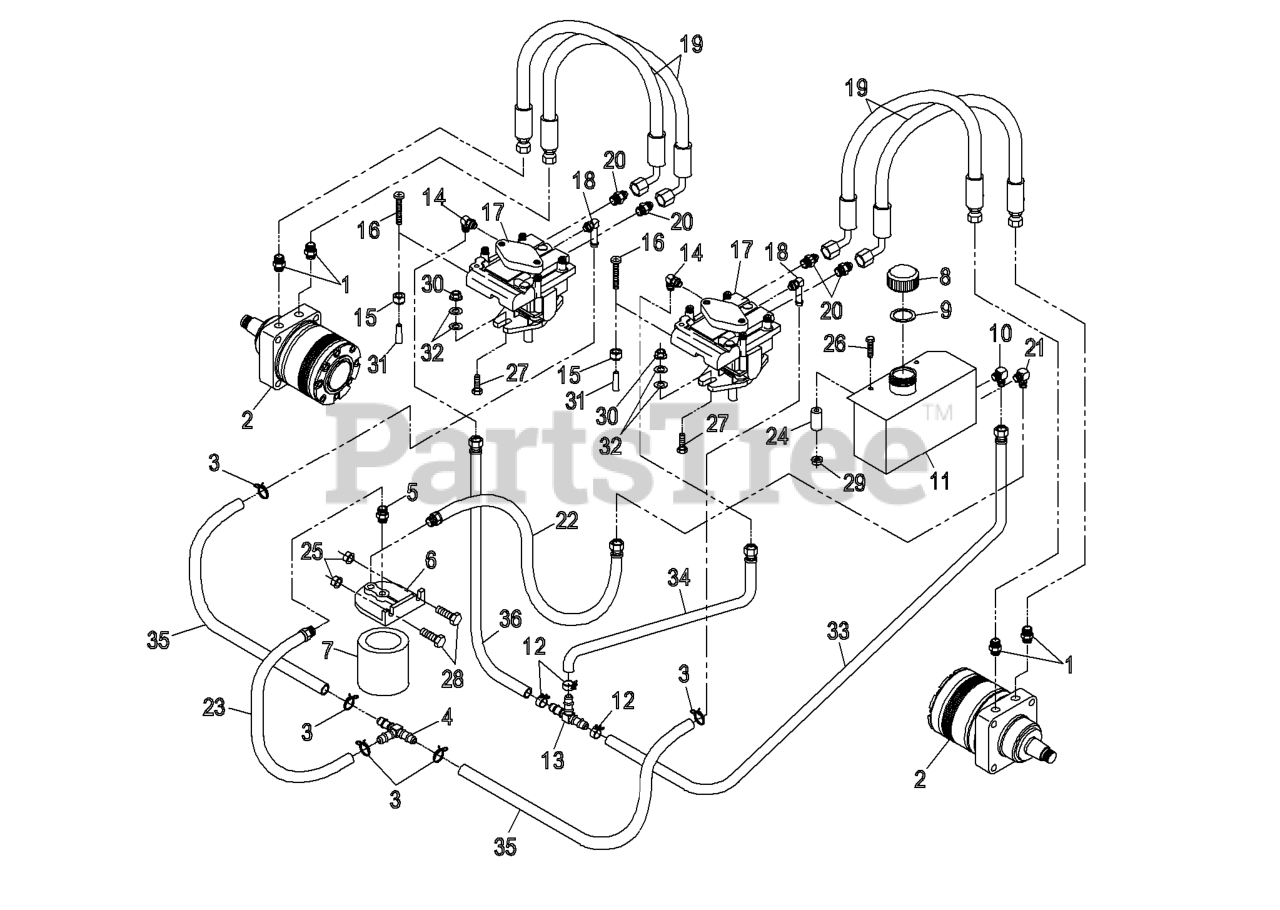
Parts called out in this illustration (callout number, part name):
1	FITTING-STRAIGHT
2	HYD MOTOR ASM
3	CLAMP-HOSE
4	FITTING-TEE, HOSE
5	FITTING-STRAIGHT
9	GASKET-CAP, TANK
10	FITTING-ELBOW
12	CLAMP-HOSE
13	FITTING-TEE, HOSE
14	FITTING-90 DEG
15	NUT-LOCK, NI
18	FITTING
19	HOSE-PRESSURE, HIGH
20	FITTING-STRAIGHT
21	FITTING-ELBOW
22	ASM,HOSE LO PRESSURE
23	ASM,HOSE CHARGE LINE
26	SCREW-HH
27	SCREW-HH
28	SCREW-HH
30	NUT-HHF, WHIZ
31	GRIP-VALVE, DUMP
32	WASHER-FLAT
33	ASM,HOSE CASE DRAIN
34	HOSE ASM
36	HOSE ASM
